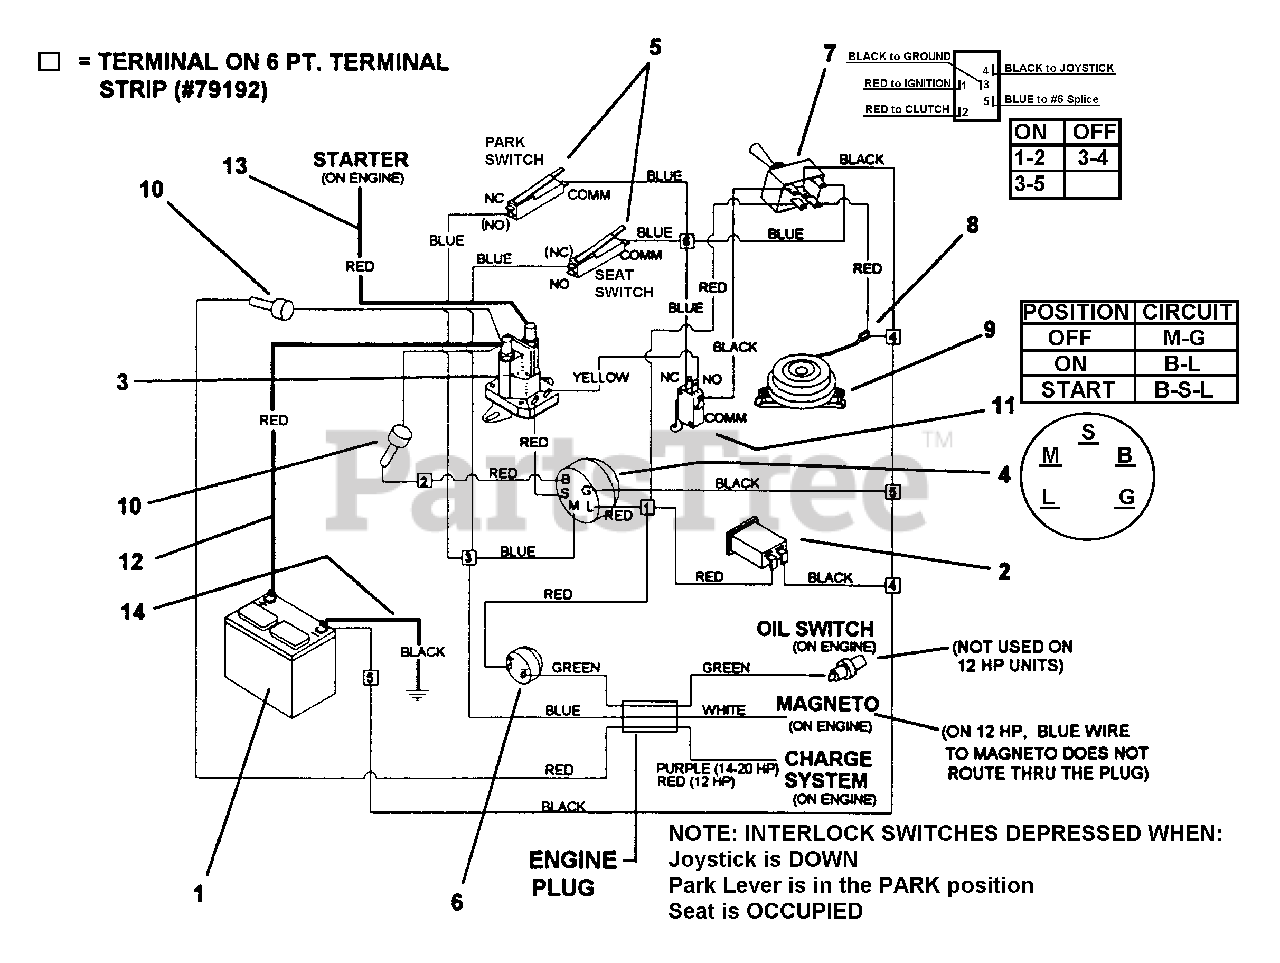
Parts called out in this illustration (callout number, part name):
1	BATTERY
2	HOUR METER, 14, 18, & 20 HP
3	SOLENOID
4	START SWITCH
5	SWITCH, ENCL, SPDT 15A HINGED LEVER
6	BUZZER, 14, 18, & 20 HP
7	CLUTCH SWITCH
8	INSULATOR COVER
9	ELECTRIC CLUTCH
10	FUSEHOLDER
10	FUSE, 20 AMP GLASS SLO-BLO
11	SWITCH, SPDT MINIATURE
12	CABLE, BATTERY, 31.75" W/BOOTS
13	CABLE, STARTER, 31.75" WO/BOOTS
14	WIRE ASS'Y, 24" BLK. 8 GA. ENG./GRD., 14, 18, & 20 HP
14	WIRE ASS'Y, 21" BLK. 8 GA. ENG./GRD., 12 HP
